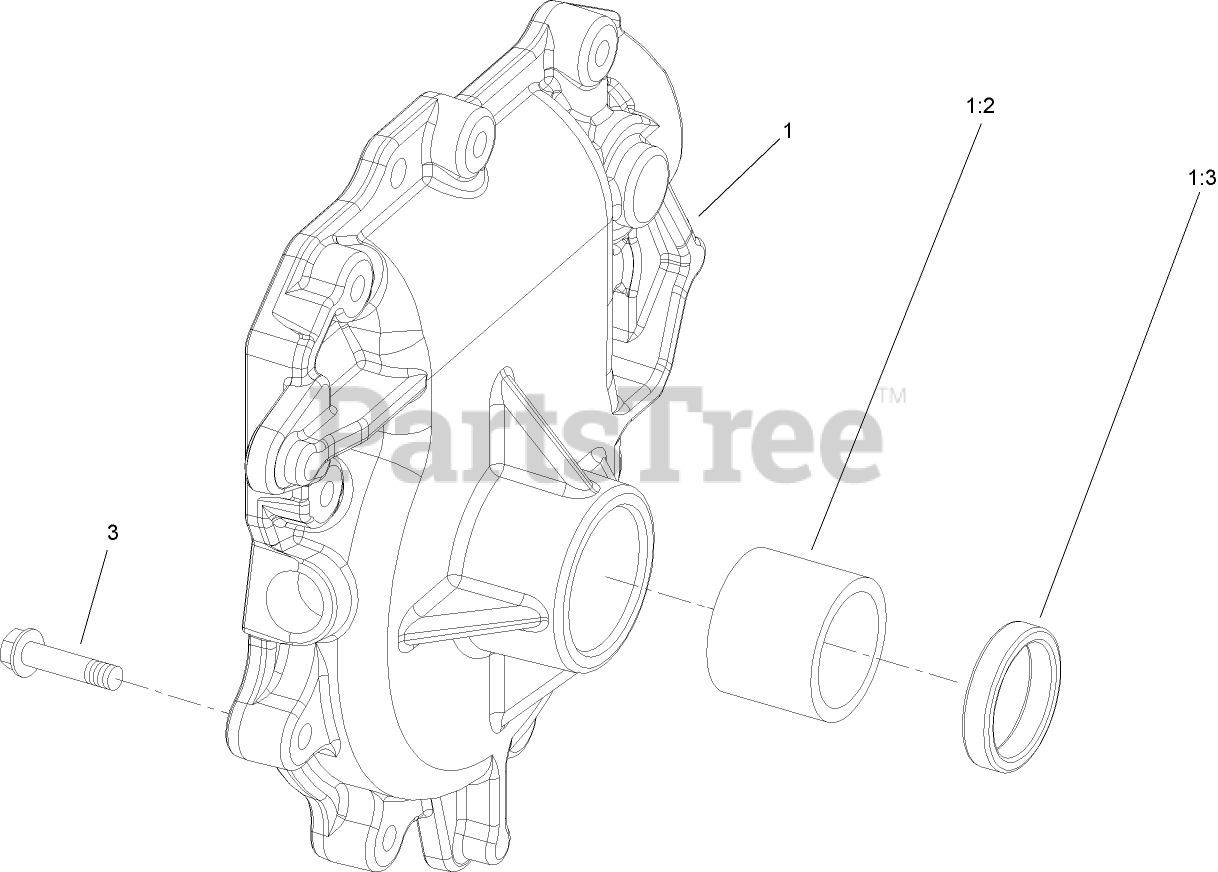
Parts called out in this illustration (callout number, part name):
1	Loose Parts Package
1:2	BUSHING
1:3	SEAL-OIL
3	SCREW-HWHTF
